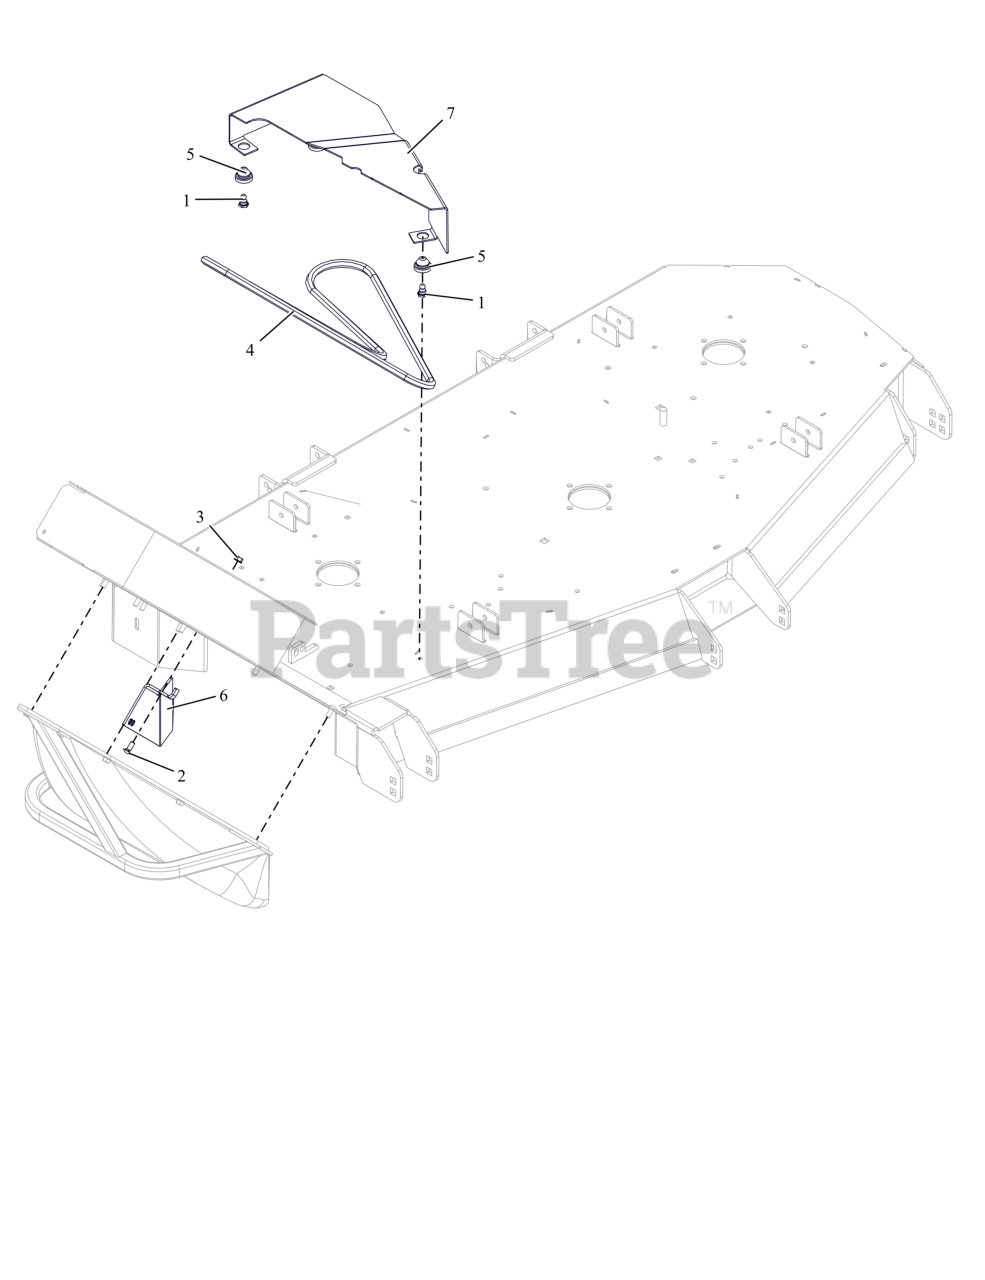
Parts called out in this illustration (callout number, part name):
1	STUD, BALL FEMALE .250-20 THREAD
2	BLT, RHSSN.31-18X.750 G5 ZCC
3	NUT,LK-CTR-FLG .31-18 GF ZCC
4	HEX BELT, HAA SECTION
5	COUPLING, RUBBER PUSH-IN
6	BRKT, PT600 60" BAGGER DISCH (BLACK)
7	GUARD, RH BLOWER DECK BELT (BLACK)
